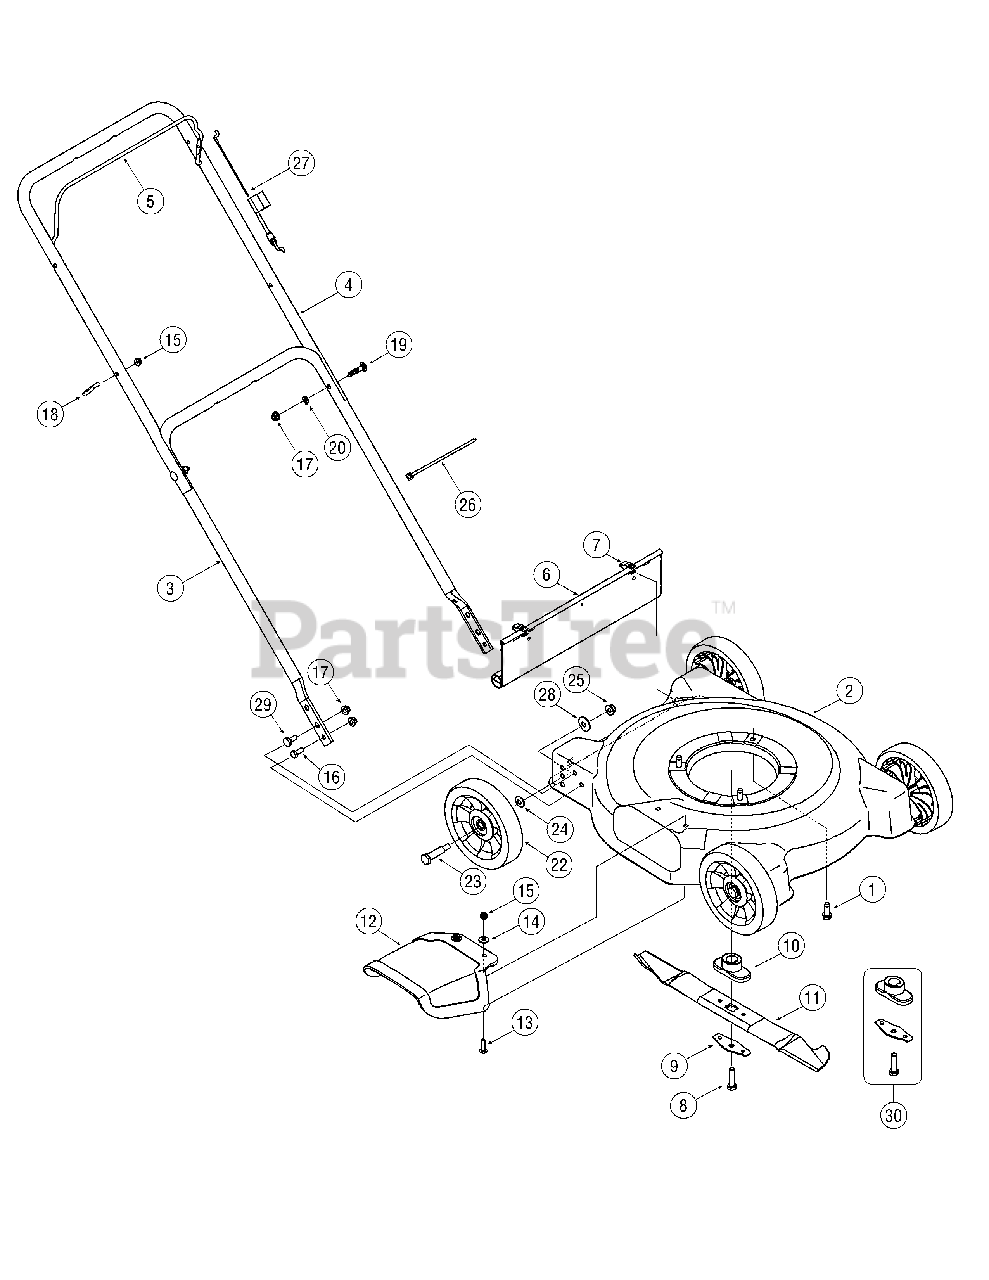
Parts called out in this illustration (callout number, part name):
1	Hex Wash HD Tap Scr 3/8-16 x .88
7	Hinge Clip
8	Hex Bolt 3/8-24 x 1.5"Lg. (Gr 8)
9	Blade Bell Support
10	Blade Adapter
11	Blade, Centre Star, 20"
12	Fixed Side Chute
13	Carriage Bolt 1/4-20 x 1.00"Lg.
14	Flat Washer .28 ID x .74 OD x .063
15	Flanged Lock Nut 1/4-20 Gr.F Nylon
16	Hex Bolt 5/16-18 x .75" Lg.Gr. 5
17	Flanged Lock Nut 5/16-18 Gr.F Nylon
18	Rope Guide Bolt
19	Carriage Bolt 5/16-18 x 1.50 Gr.2
20	L-Wash 5/16 ID
22	Front Wheel Ass’y 7 Star Diamond, Grey
23	Shoulder Screw .498"DIA. x 1.64
24	Cupped Washer .375 ID x .870 OD x .063
25	Flanged Lock Nut 3/8-16 Gr.F Nylon
27	Control Cable 37.25"Lg. (B&S)
28	Cupped Washer .39 ID x 1,12 OD
29	Shoulder Screw, 3/8-16 x .428
30	Blade Adapter Kit
